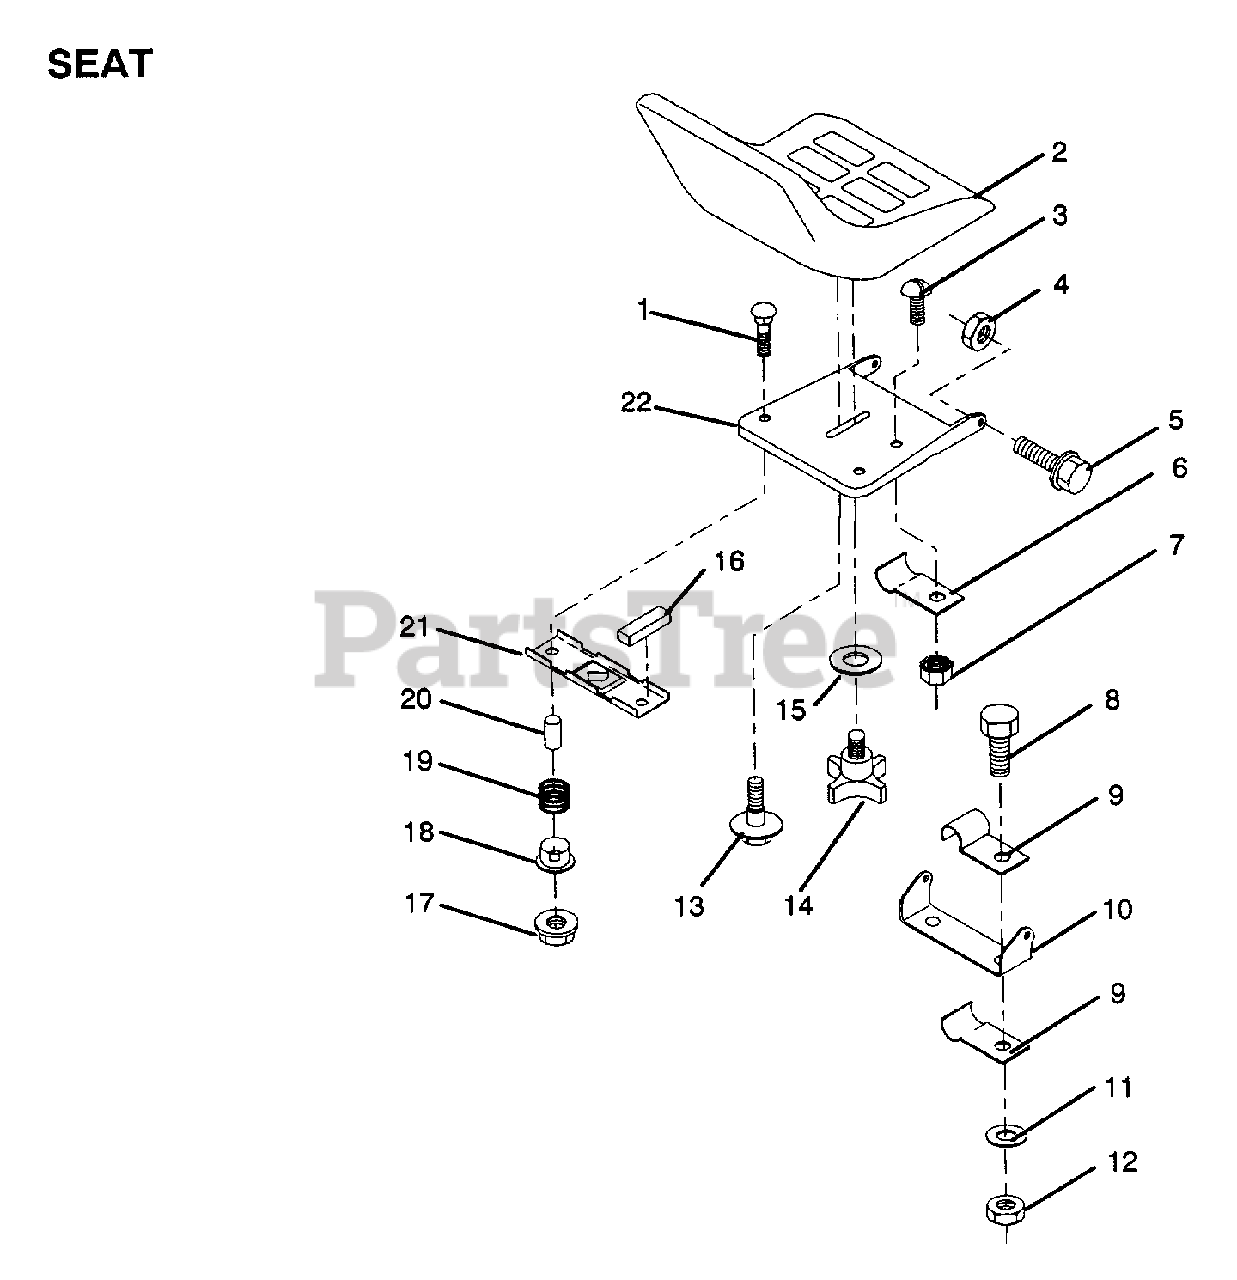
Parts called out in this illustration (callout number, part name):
1	BOLT
7	"NUT,KEPS"
9	"CLIP,INSULATOR"
11	WASHER
13	"BOLT,SHOULDER"
14	"KNOB 1/2"" YT"
15	WASHER
16	STRIP FORM
18	BUSHING
19	SPRING
20	SPACER SPLIT
21	BRKT SWITCH
